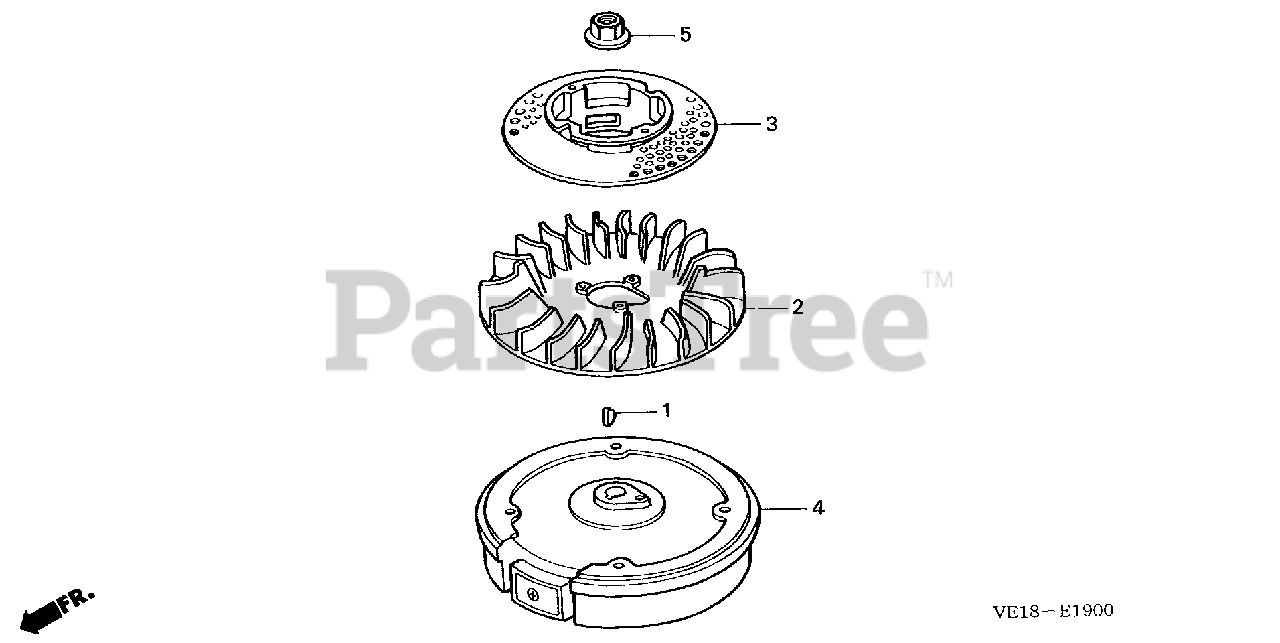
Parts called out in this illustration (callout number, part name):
1	KEY, SPECIAL WOODRUFF (25X18)
2	FAN, COOLING
3	PULLEY, STARTER
5	NUT, SPECIAL (14MM)
